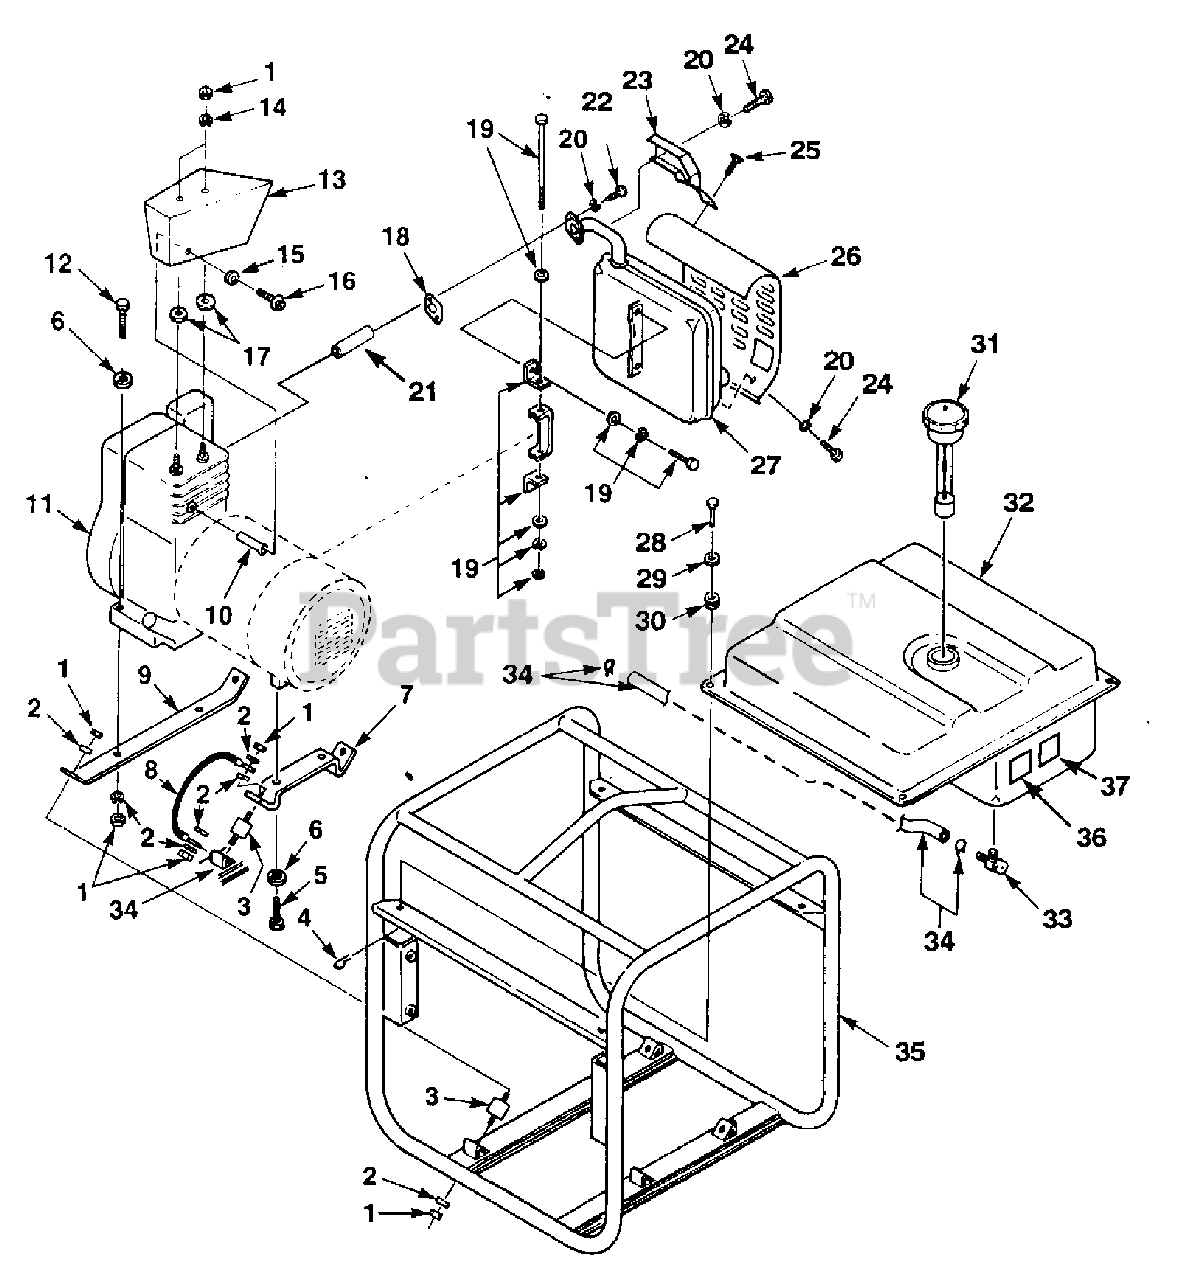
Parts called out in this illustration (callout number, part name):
1	NUT- (5/16-18")
2	WASHER-Lock Int.
3	ISOLATOR-Vibration
4	PIN-Cottor Hair
5	SCREW-Hex Tapping (5/16-18 X 1")
6	WASHER-Lock Int.
7	SUPPORT-Generator
8	GROUND STRAP
9	SUPPORT-Engine
12	SCREW-Hex Hd. (5/16-18 X 2")
13	DEFLECTOR-Air
14	WASHER-Lock
15	WASHER-Flat(#10)
16	SCREW (10-24 X 1 1/2")
17	WASHER-Flat (5/16")
18	GASKET-Muffler
19	MUFFLER BRACKET KIT
20	WASHER (1/4")
21	STUD-Cylinder
22	NUT-Hex
23	SHIELD-Exhaust
24	SCREW-Hex Cap (14-20 X 1 1/8")
25	SCREW-Tap Pan Hd. (#8-18 X 3/8")
26	SHIELD-Muffler
27	MUFFLER
28	PIN-Clevis
29	WASHER-Flat (1/4")
30	GROMMET-Isolator
31	CAP-Fuel
32	FUEL TANK
33	VALVE-Fuel
34	FUEL LINE ASSEMBLY (See Note 2)
35	ROLL CAGE
36	DECAL-Fuel Valve
37	DECAL- Caution
